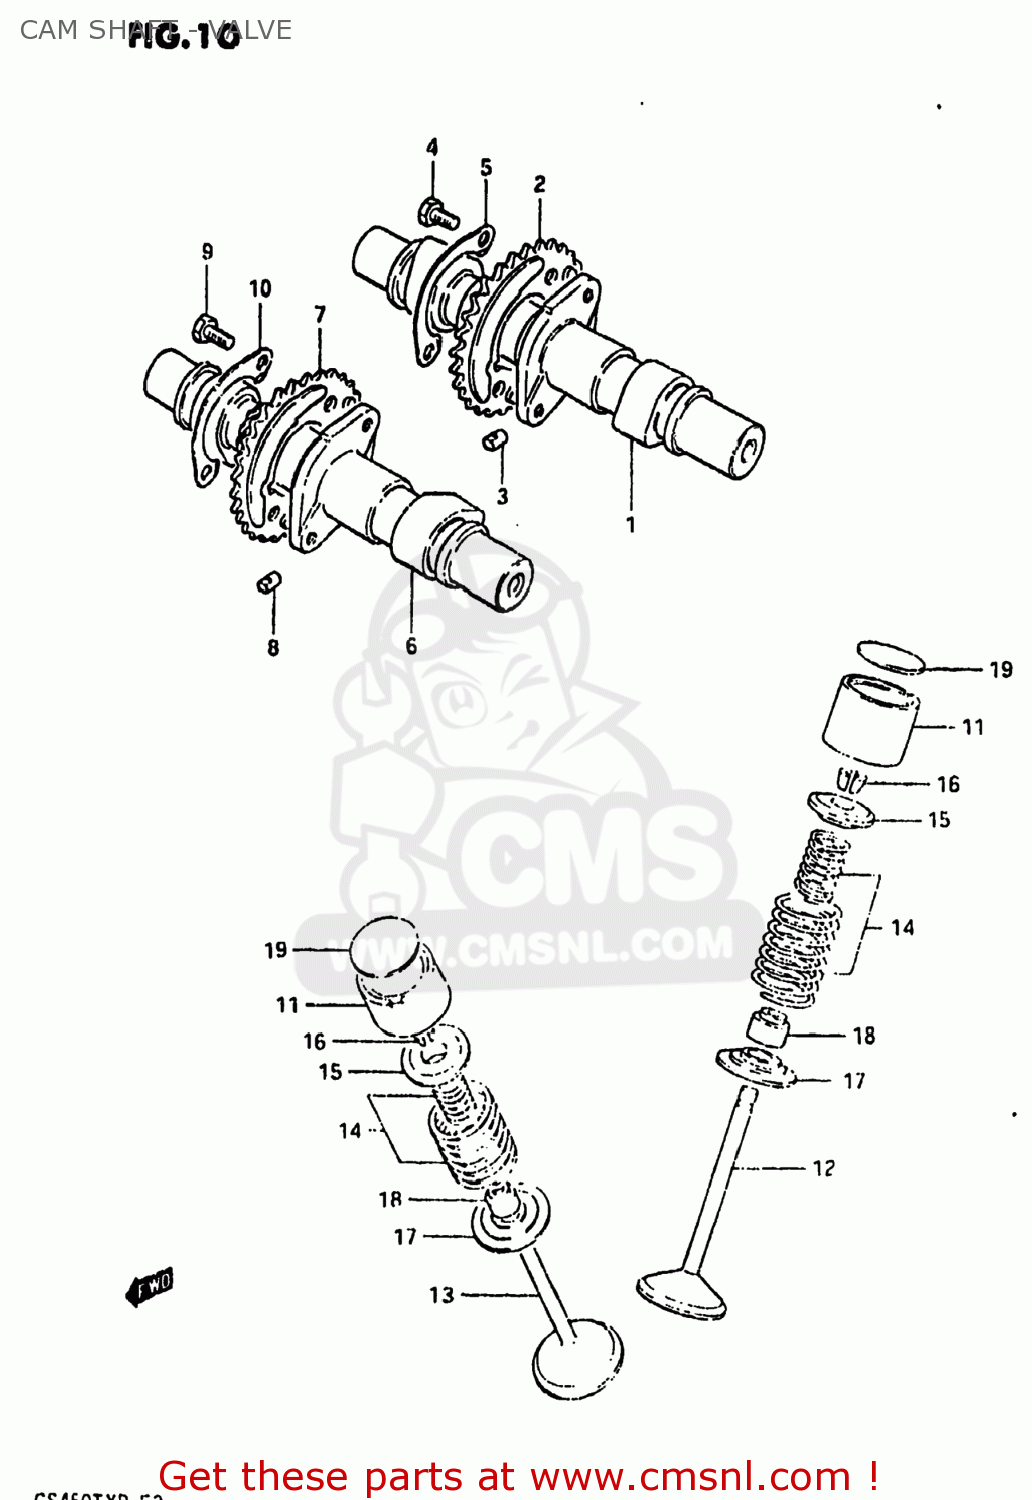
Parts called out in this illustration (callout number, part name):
1	CAMSHAFT,INTAKE
2	SPROCKET,CAMSHAFT
3	PIN,SPROCKET
4	BOLT(6X12.5)
5	WASHER,CAM CHAIN SPROCKET
6	CAMSHAFT,EXHAUST
7	SPROCKET,EXHAUST CAM(NT:30)
8	PIN,SPROCKET
9	BOLT(6X12.5)
10	WASHER,CAM CHAIN SPROCKET
11	TAPPET
12	VALVE,INTAKE
13	VALVE,EXHAUST
14	SPRING SET,VALVE
15	RETAINER,VALVE SPRING
16	COTTER VALVE
17	SEAT,VALVE SPRING
18	SEAL,OIL(7X14.4X9)
19	SHIM,TAPPET
20	SHIM SET,TAPPET
21	CASE
